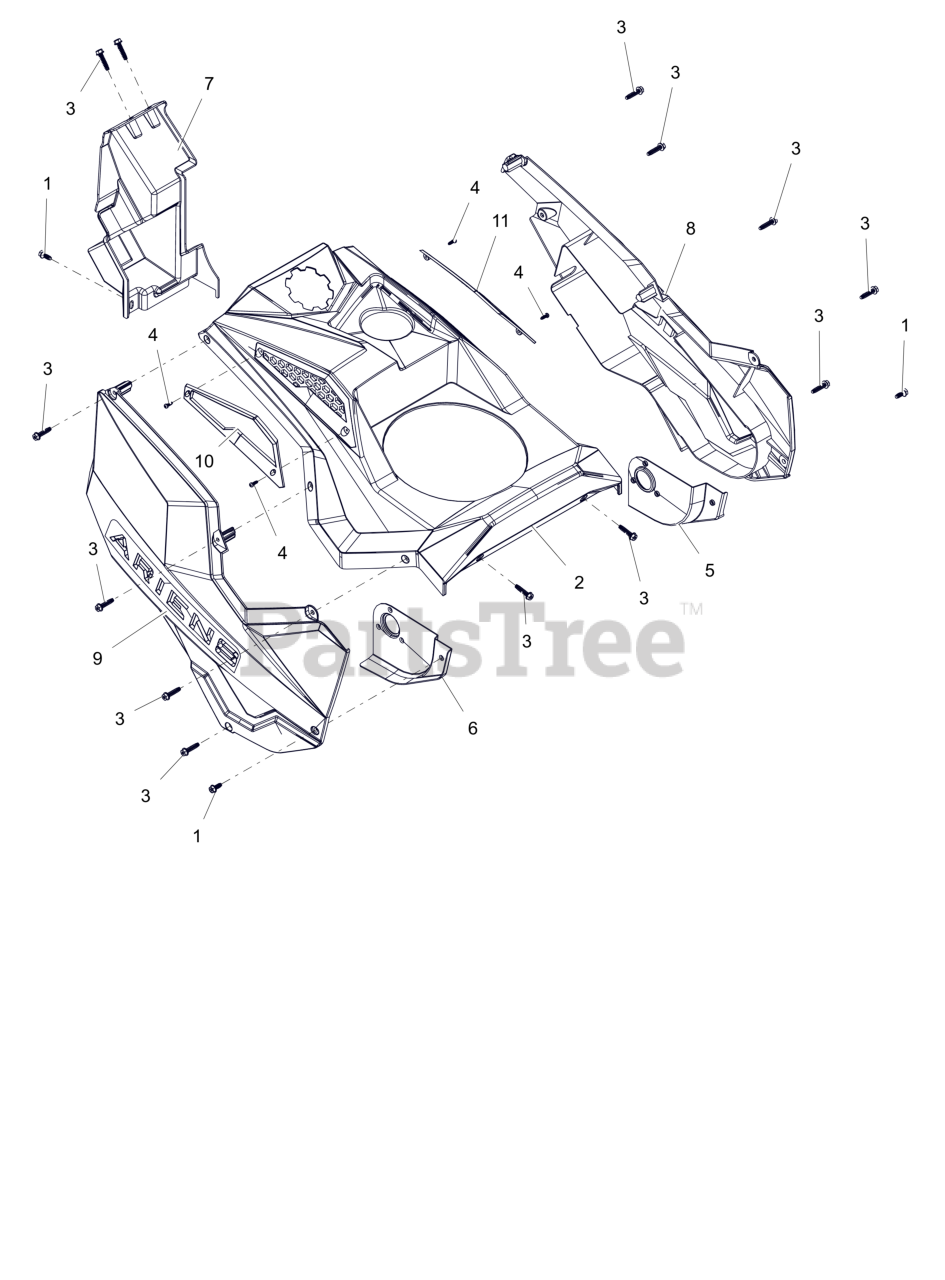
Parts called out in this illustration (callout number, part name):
1	1/4-20 X 5/8 TAPTITE
2	SHROUD, UPPER
3	1/4"-10x1.12 TRI-LOBE SCREW
4	M4x12 DELTA PT TRS SCREW
5	STAMPING, INNER LH
6	STAMPING, INNER - RH
7	PANEL, REAR
8	SHROUD, LEFT
9	SHROUD, RIGHT
10	TRIM, RH VENT
11	TRIM, LH VENT
